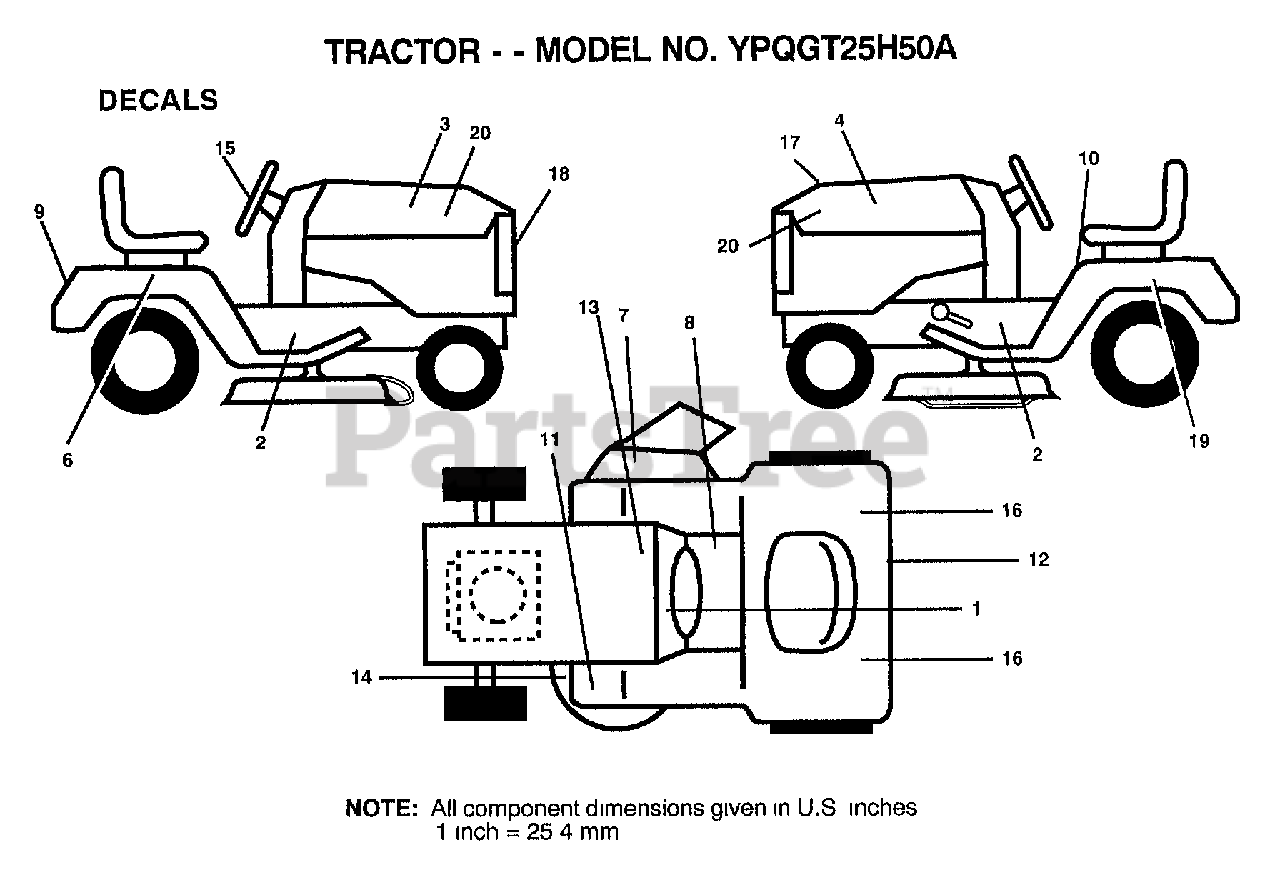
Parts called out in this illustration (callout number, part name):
1	DECAL OPER INSTR.
2	DECAL CHASSIS 50
6	DECAL FENDER RH
7	"DECAL, WARNING"
8	DECAL BRAK PARK
9	DECAL FENDER
10	DECAL.CAUT.ENG/FR
11	DECAL T
12	DECAL D-BAR CNTRL
13	DECAL.BATRY.3-3908
15	DECAL INS STRG WH
16	REFLECTOR-TAIL YT
18	DECAL GRILLE
19	DECAL FENDER LH
20	DECAL.DASH
